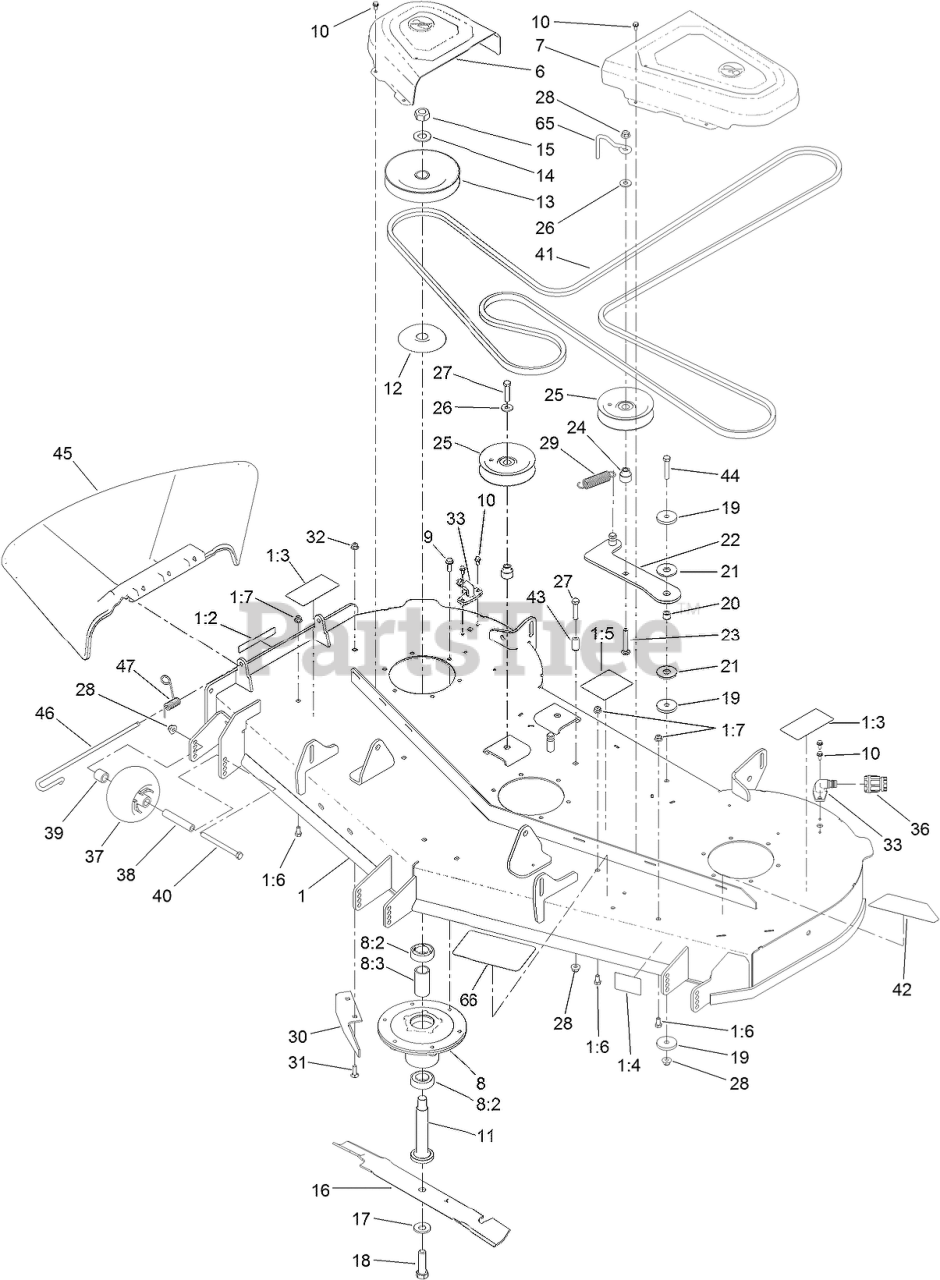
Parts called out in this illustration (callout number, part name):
1	DECK ASM
1:2	DECAL-DANGER
1:3	DECAL-DANGER, DECK
1:4	DECAL-SCALP, ANTI
1:5	DECAL-ROUTING, BELT
1:6	SCREW-HH
1:7	NUT-HF, NI
6	COVER-BELT, RH
7	COVER-BELT, LH
8	SPINDLE ASM
8:2	BEARING-BALL
8:3	SPACER-BEARING
9	SCREW-TAPTITE
10	SCREW-HWH
11	SHAFT-SPINDLE
12	SHIELD-BEARING
13	PULLEY
14	WASHER
15	NUT-HEX
16	BLADE-HI FLOW, 20.5 INCH
17	WASHER-BELLEVILLE
18	SCREW-BLADE
19	WASHER-PLAIN
20	BUSHING-LEVER, LIFT
21	WASHER-FRICTION, COMPOSITE
22	ARM-IDLER
23	SCREW-CARR
24	BUSHING-IDLER
25	PULLEY-IDLER, FLAT
26	WASHER-HARDENED
27	SCREW-HH
28	NUT-HF, NI
29	SPRING-EXTENSION
30	BAFFLE-CUTOFF
31	SCREW-CARR
32	NUT-HF, NI
33	FITTING-WASHOUT
36	CONNECTOR-HOSE
37	ROLLER-SCALP, ANTI
38	TUBE-SPANNER
39	SPACER-AXLE, REAR
40	SCREW-HH
41	V-BELT
43	SPACER
44	SCREW-HH
45	DEFLECTOR-DISCHARGE
46	PIN-CHUTE
47	SPRING-TORSION
65	GUIDE-BELT, IDLER
66	TREAD-STEP
